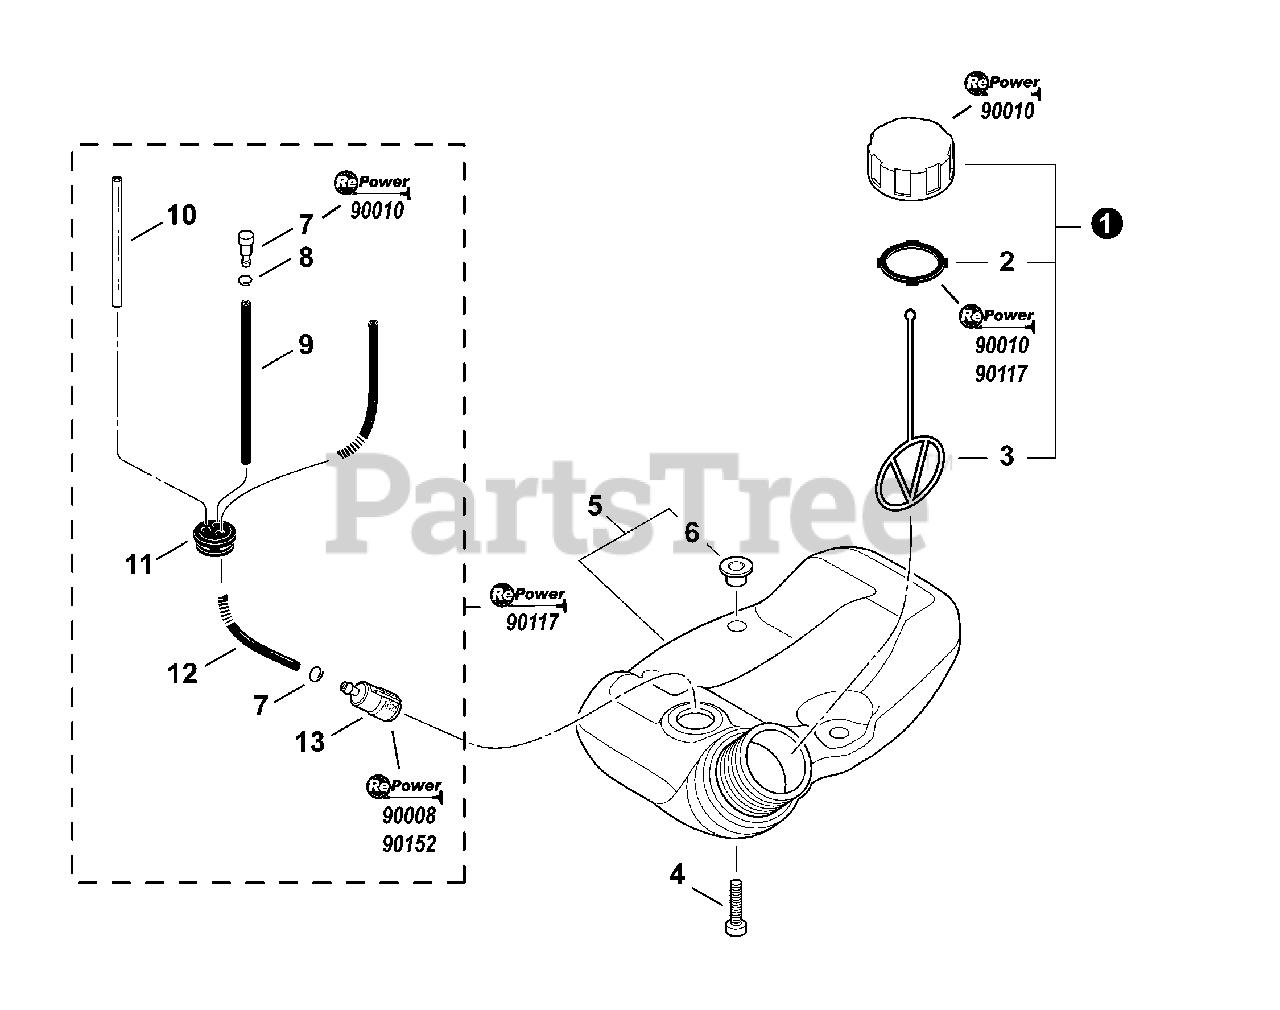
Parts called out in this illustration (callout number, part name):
1	CAP ASSY, FUEL
2	GASKET, FUEL CAP
3	CONNECTOR, CAP L= 123
4	BOLT, TORX 5×20
5	TANK ASSY, FUEL
6	COLLAR 5
7	CLIP 6 MM
8	VENT ASSY
9	PIPE, FUEL 3×6×80 CLEAR
10	PIPE, FUEL 3×5×90 BLACK
11	GROMMET, FUEL
12	PIPE, FUEL 3×5×210 BLACK
13	FILTER, FUEL
